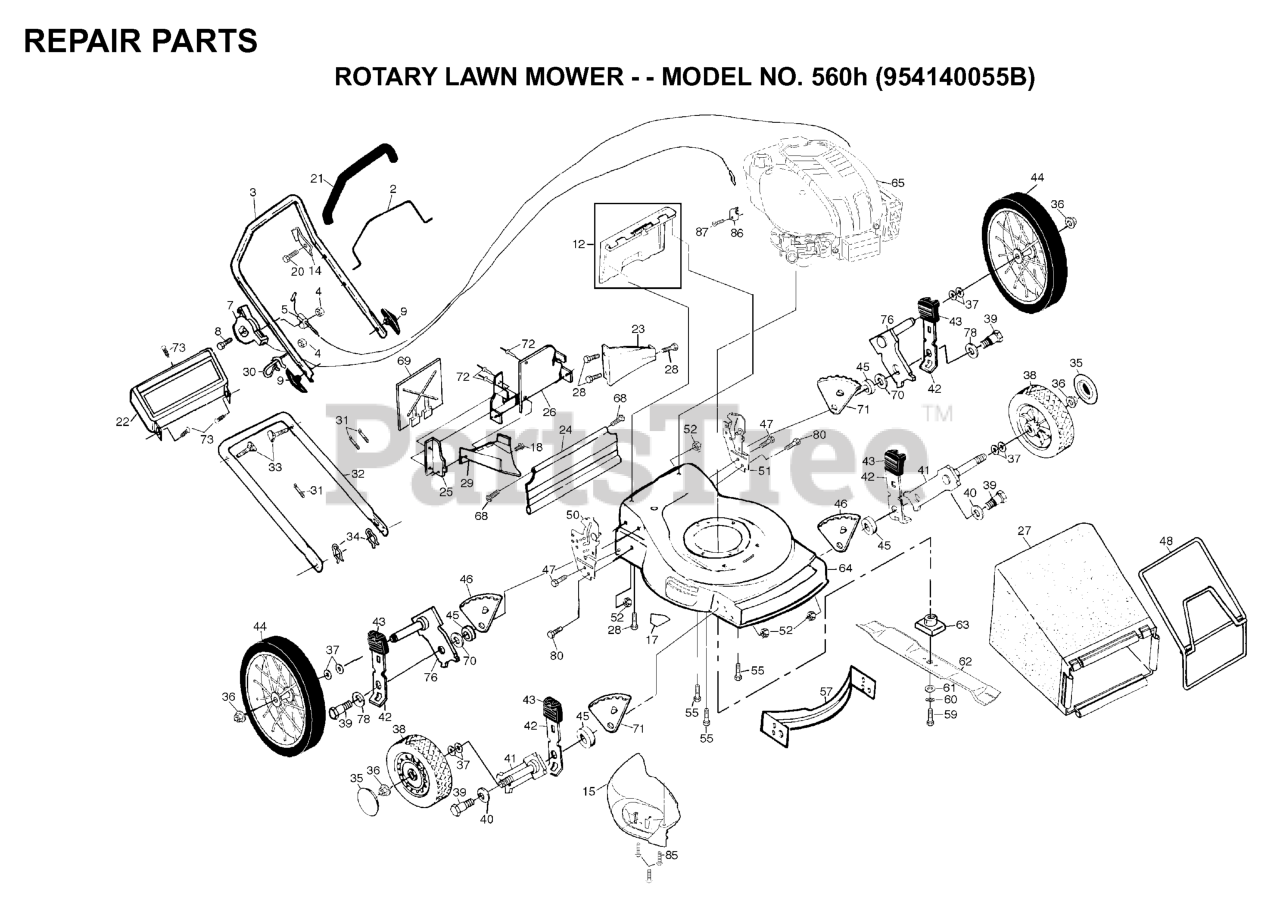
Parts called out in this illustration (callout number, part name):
2	CONTROL BAR/BLACK
4	NUT
5	CABLE.MZR.51.RT.SP./PU.
7	THROTTLE CONTROL
8	SCREW 1/4-20 X 2.12
9	HANDLE KNOB
14	BRACKET UPSTOP
17	DECAL HYT
18	SCREW.HXTAP.10-24
20	TAPPING SCREW
21	GRIP.HANDLE.FOAM
22	TRIM PLATE
23	REAR BAFFLE
24	REAR SKIRT
25	SIDE BAFFLE
26	BACK PLATE
27	GRASS BAG
29	DISCHARGE BAFFLE
30	ROPE GUIDE
31	TIE GUIDE
32	HANDLE, LOWER
33	HANDLE BOLT
34	HAIRPIN COTTER
35	HUBCAP.8".GREY
36	HEX FLANGE LOCKNT
37	WAVE WASHER
38	WHEEL.8X2.PR.LP.RAD.GREY
39	BOLT
40	WASHER.BELLEVILLE (3 2 LB)
41	AXLE ARM
42	SELECTOR SPRING
43	SELECTOR KNOB
44	WHEEL TIRE PM
45	RP SPACER HT ADJ
46	WHL ADJ BRKT LF/RR
47	SELF-TAPPING SCREW 5/16-18X3/4
48	CATCHER.FRAME.WALK
51	BRACKET
52	LOCKNUT PM
55	BOLT 3/8-16X1-1/8
57	BAFFLE
59	SCREW, HEX HD 3/8-24 X 1-3/8
60	LOCKWASHER
61	WASHER,HARDEN
63	BLADE ADAPTOR
68	HINGE SCREW
69	MULCHER PLATE
70	WASHER.FLAT.1/2
71	WHL ADJ BRKT RF/LR
72	RIVET BLIND
85	SCREW.PAN.HEAD.#10
86	CABLE CLAMP(ENGINE)
87	SCREW.HEX.HEAD.WASHER.10-16
